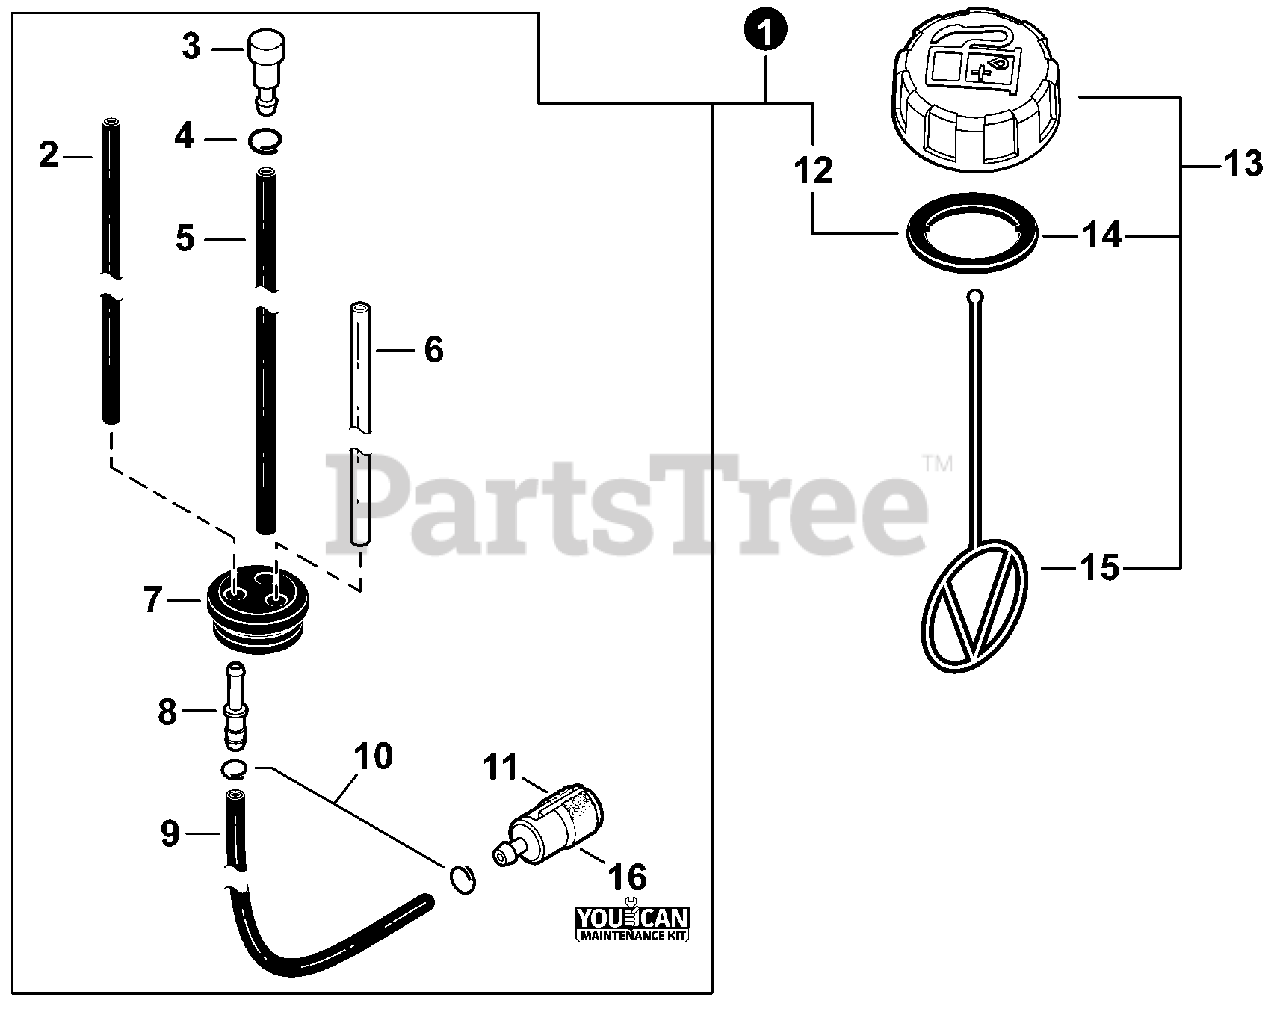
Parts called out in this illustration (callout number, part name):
1	FUEL SYSTEM KIT
2	PIPE, FUEL - 3×5×67 - BLACK
3	VENT ASSY
4	CLIP Ø6.5 MM
5	PIPE 3×6×115 BLACK
6	PIPE, FUEL 3×6×80 CLEAR
7	GROMMET, FUEL
8	CONNECTOR, PIPE Ø5ר3.5
9	PIPE, FUEL - 3×5×125 - BLACK
10	CLIP Ø6
11	FILTER, FUEL
12	GASKET, FUEL CAP
13	CAP ASSY, FUEL
14	GASKET, FUEL CAP
15	CONNECTOR, CAP L= 100 MM
16	TUNE-UP KIT - YOUCANT
